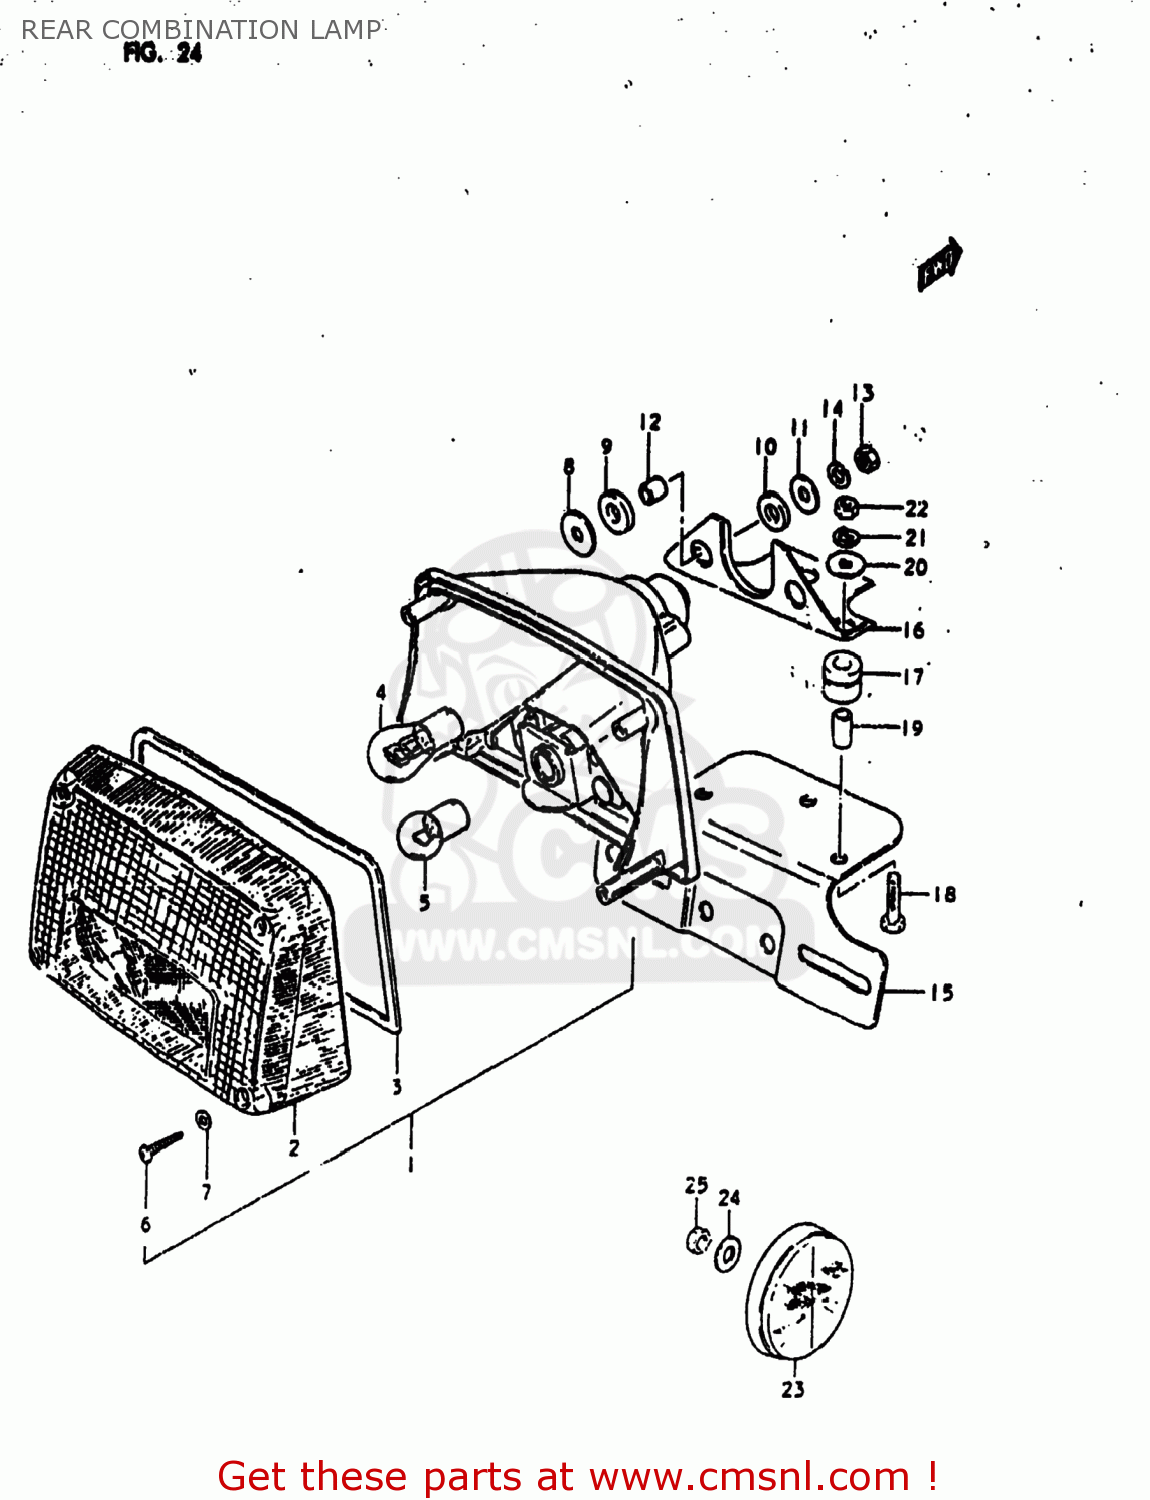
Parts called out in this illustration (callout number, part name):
1	LAMP ASSEMBLY,REAR COMBINATION
2	LENS
3	GASKET (NAS)
4	BULB(12V23W)
5	BULB
6	BOLT
7	GASKET (NAS)
8	WASHER
9	CUSHION
10	CUSHION
11	WASHER(6,5X22X1.6)
12	SPACER(6.1X9X7.5)
13	NUT
14	LOCK WASHER
15	PLATE,REAR LICENSE
16	BRACKET,LICENSE PLATE
17	CUSHION, BRACKET
18	BOLT
19	SPACER (6.4X9X15.5)
20	WASHER
21	LOCK WASHER
22	NUT
23	REFLEX REFLECTOR,RR
24	WASHER
25	NUT
